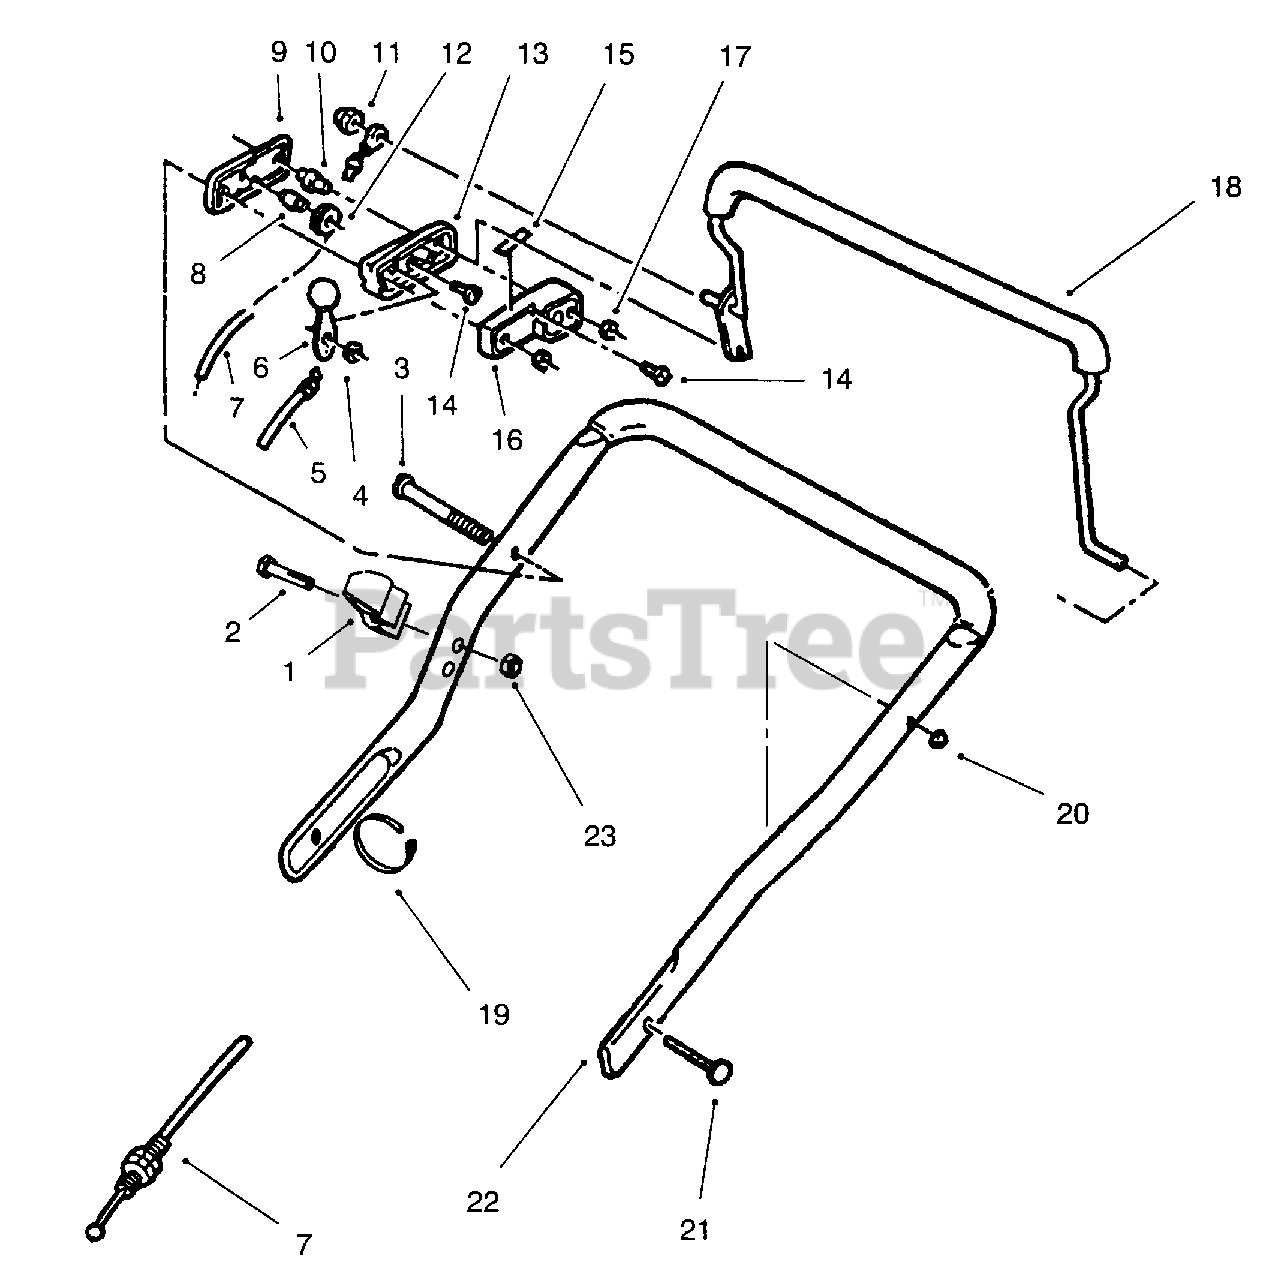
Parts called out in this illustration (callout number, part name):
1	Guide-Rope
5	Cable-Throttle
6	Lever & Knob Assembly
7	Cable-Control
9	Control Case Outer
11	Nut-Acorn
13	Case-Throttle, Center
15	Decal-Throttle
16	Case-Throttle, Inner
18	Lever-Control
19	Tie Strap
20	Nut-Push
22	Handle Assembly-Top
23	Nut-Lock
